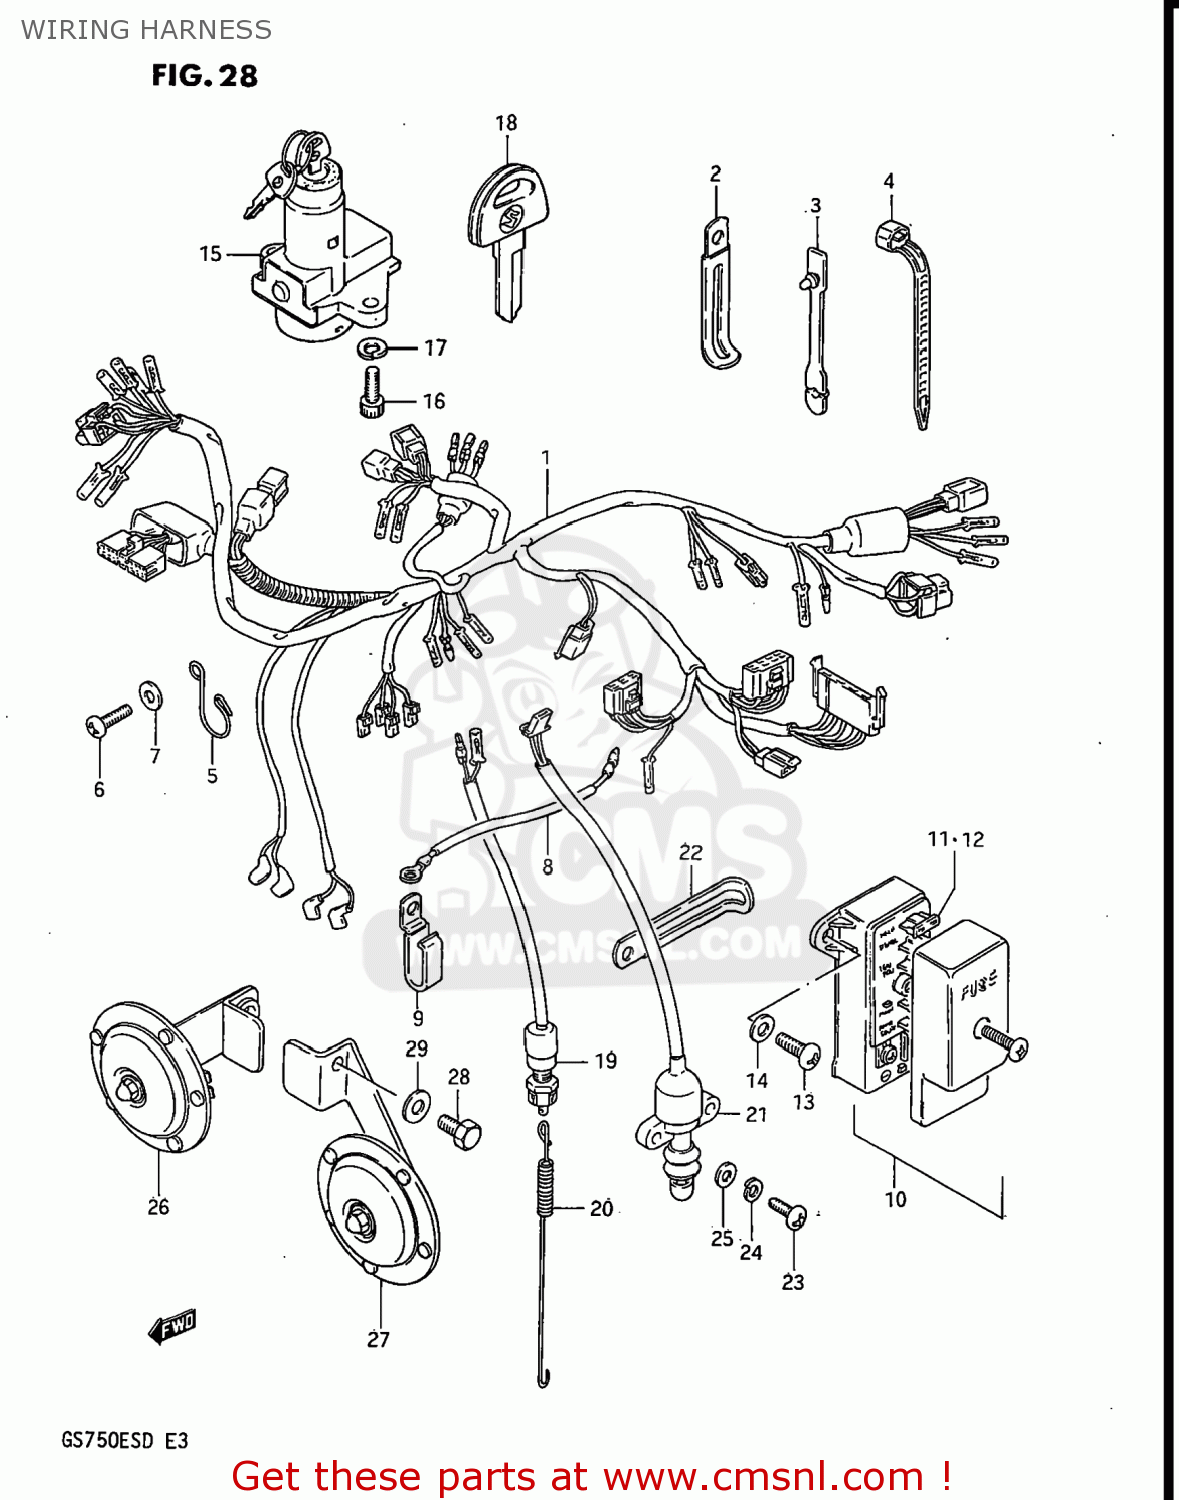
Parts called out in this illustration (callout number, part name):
1	HARNESS,WIRING
2	CLAMP
3	CLAMP,L:88
4	CLAMP(L:95)
5	CLIP,WIRING HARNESS
6	SCREW 6X12
7	WASHER
8	WIRE
9	CLAMP
10	BOX ASSEMBLY,FUSE
11	FUSE(10A)
12	FUSE(15A)
13	SCREW 6X12
14	WASHER
15	LOCK ASSEMBLY,STEERING
16	BOLT
17	LOCK WASHER
18	KEY,BLANK
19	SWITCH ASSEMBLY,STOP LAMP
20	SPRING
21	SWITCH ASSEMBLY,SIDE STAND
22	CLAMP
23	SCREW 5X20
24	LOCK WASHER
25	WASHER
26	HORN ASSEMBLY
27	HORN ASSEMBLY
28	BOLT
29	WASHER
